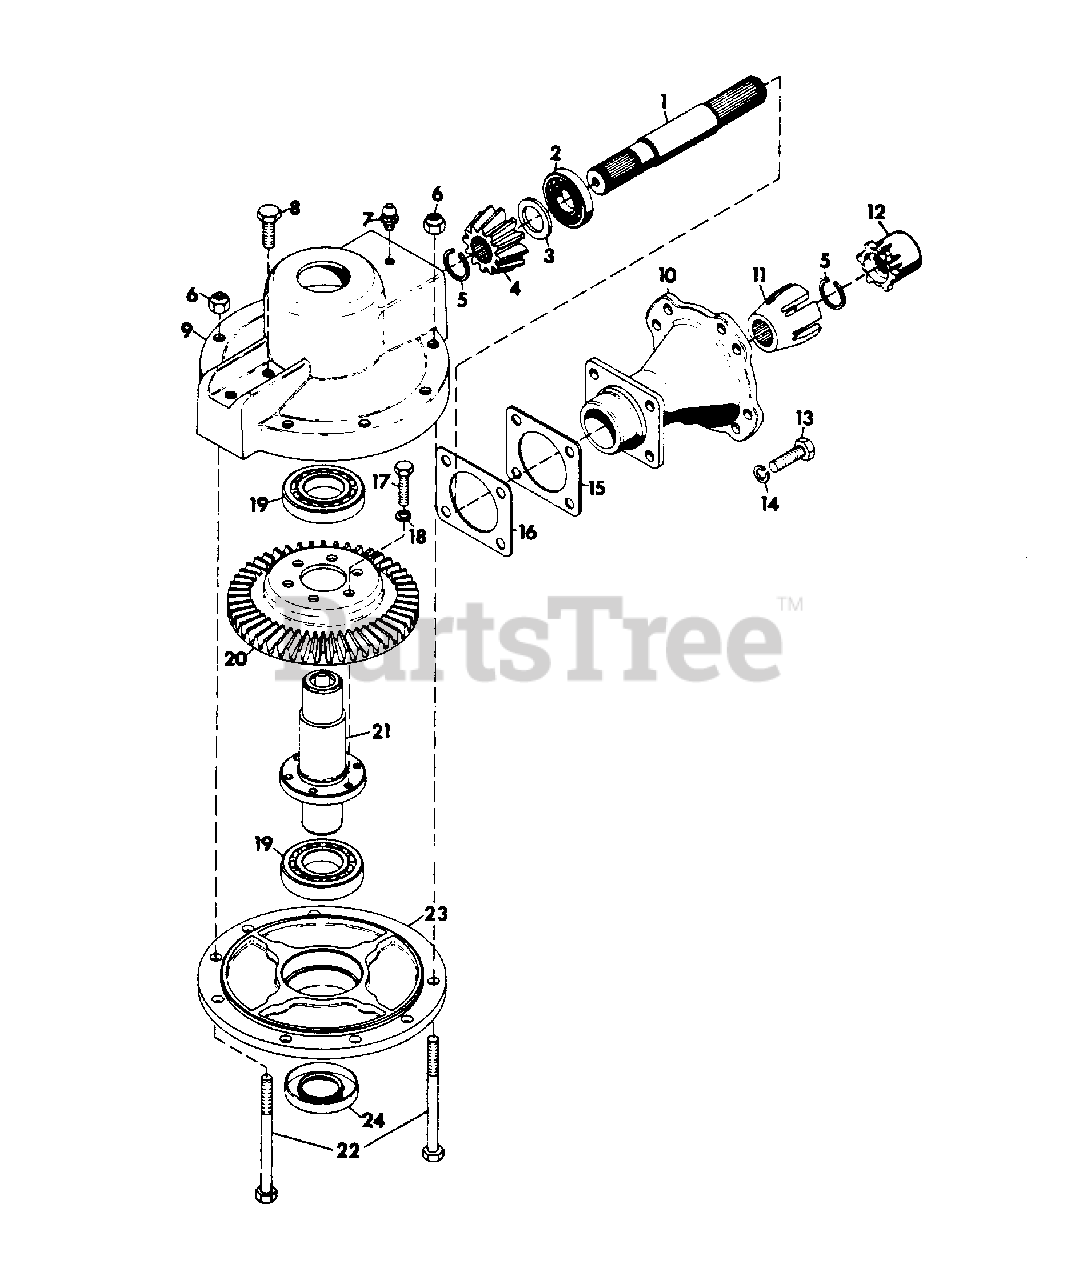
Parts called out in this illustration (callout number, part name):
1	SHAFT, DRIVE
2	BEARING, BALL .984X2.047X.591
3	RACE, THRUST
4	PINION, BEVEL ROTARY PLOW
5	RING, RETAINING .937 SHAFT
6	NUT, LOCK 3/8-16
7	FITTING, LUBE 1/4-28
8	BOLT, HEX 1/2-13X.75
9	HOUSING, GEAR
10	HOUSING, DRIVE SHAFT
11	CLUTCH, DOG
12	DOG, ATTACHMENT
13	BOLT, HEX 1/2-13X1.25
14	WASHER, LOCK 1/2 REG.
15	SHIM, .005
16	SHIM, .020
17	BOLT, HEX 3/8-16X.875
18	WASHER, LOCK 3/8-REG.
19	BEARING, BALL 2.155X3.543X.709
20	GEAR, BEVEL
21	HUB, BEVEL GEAR
22	BOLT, HEX 3/8-16X2.25
23	PLATE, GEAR HOUSING
24	SEAL, OIL 2.165X3.250X.375
